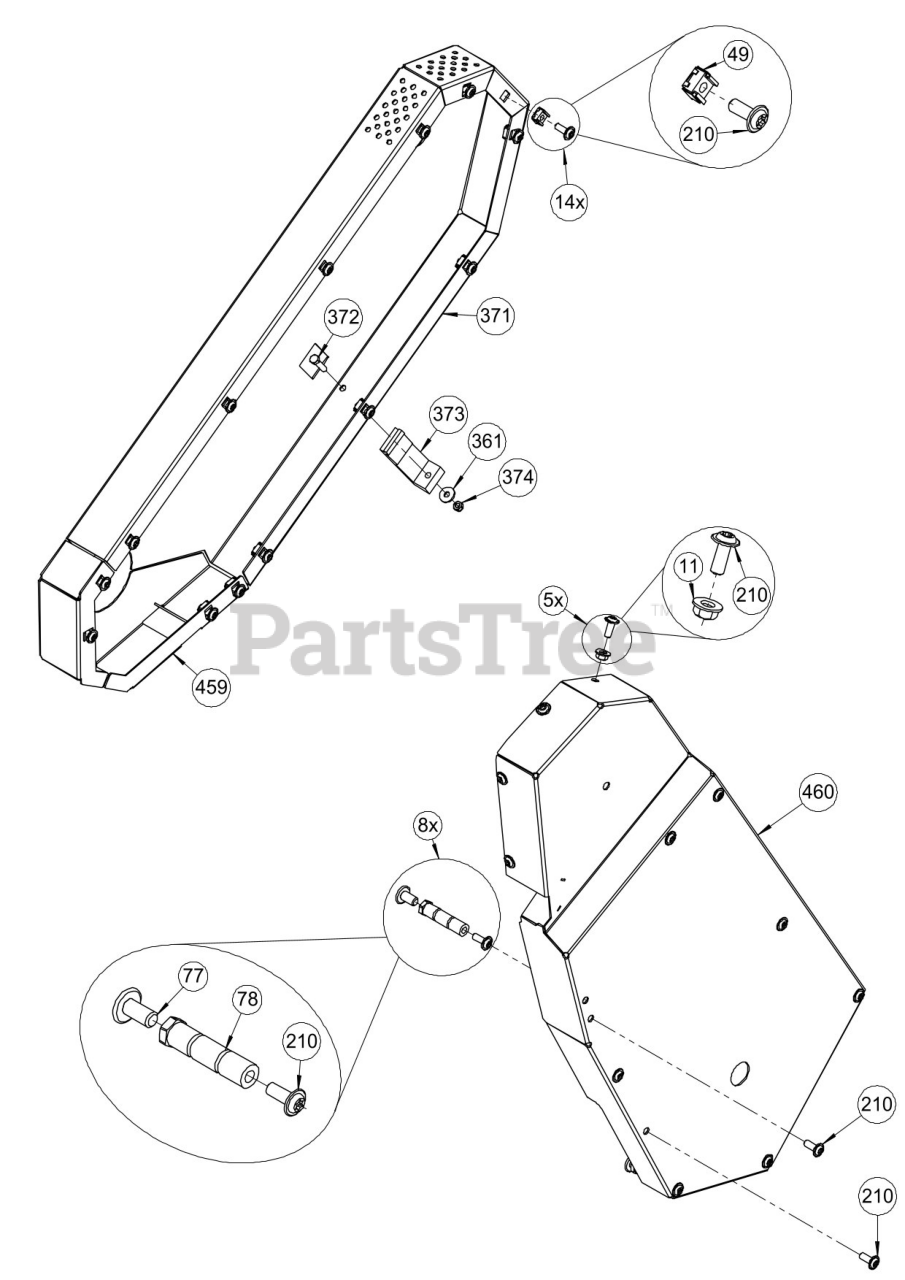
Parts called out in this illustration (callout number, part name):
11	NUT, FLG SLF LK M6 CL 8 ZCC
49	NUT, CAGE M6
77	TORX FBHCS M8X16-8.8
78	BELT GUIDE
210	TORX FBHCS M6X16-8.8
361	WSHR, FLT M5.3 DIN 9021-ST ZCC
371	BELT COVER, FINAL
372	BLT, HEX M5X20 DIN 933-8.8 ZCC
373	PAD, WEAR
374	NUT, HEX LK-NYL M5 DIN 985-8 ZCC
459	BELT COVER, FINAL
460	BELT COVER, INTERMEDIATE
